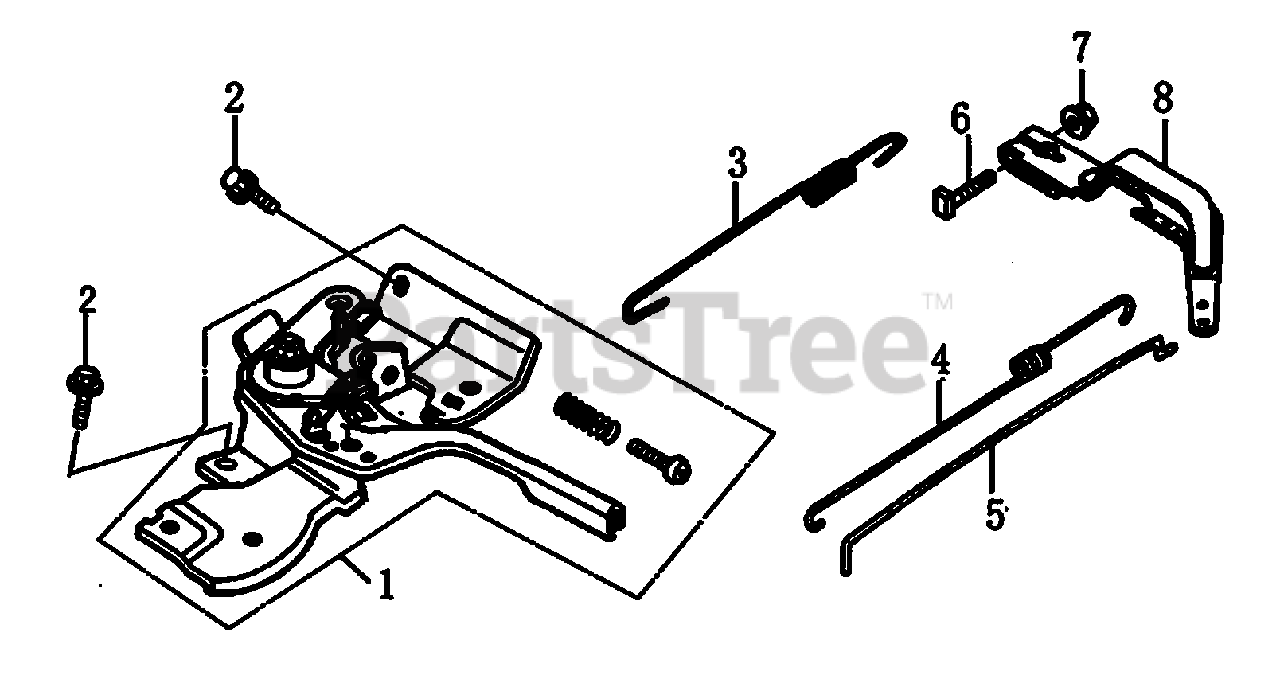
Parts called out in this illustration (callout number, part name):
1	CONTROL ASSY.
2	BOLT, FLANGE
3	SPRING, GOVERNOR
4	SPRING, THROTTLE RETURN
5	ROD, GOVERNOR
6	BOLT, GOVERNOR ARM M6X21
7	NUT, FLANGE
8	ARM, GOVERNOR
